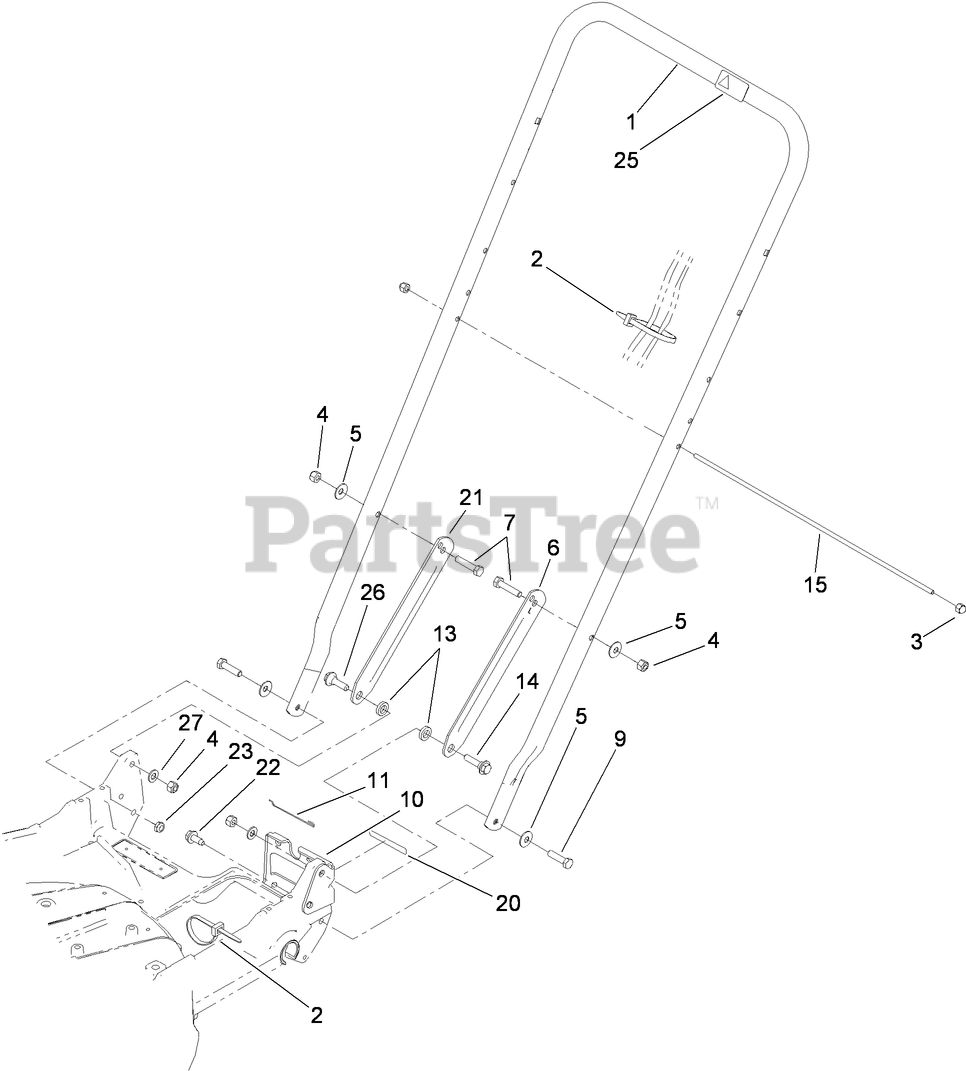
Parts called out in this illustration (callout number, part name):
2	TIE-CABLE
3	NUT-CAP
4	NUT-LOCK, NI
5	WASHER-BELLEVILLE
6	LATCH-HANDLE, LH
7	SCREW-HH
9	SCREW-HH
10	BRACKET-ADJUSTMENT, TRACTION
11	RETAINER-CABLE
13	SPACER
14	SCREW-SHOULDER
15	ROD-SUPPORT, BAG
20	DECAL-POSITION, GEAR
21	LATCH-HANDLE, RH
22	SCREW-HWHTF
23	NUT-LOCK, NI
25	DECAL-PROTECTION, EAR
26	SCREW-SHOULDER
27	WASHER-PLAIN
